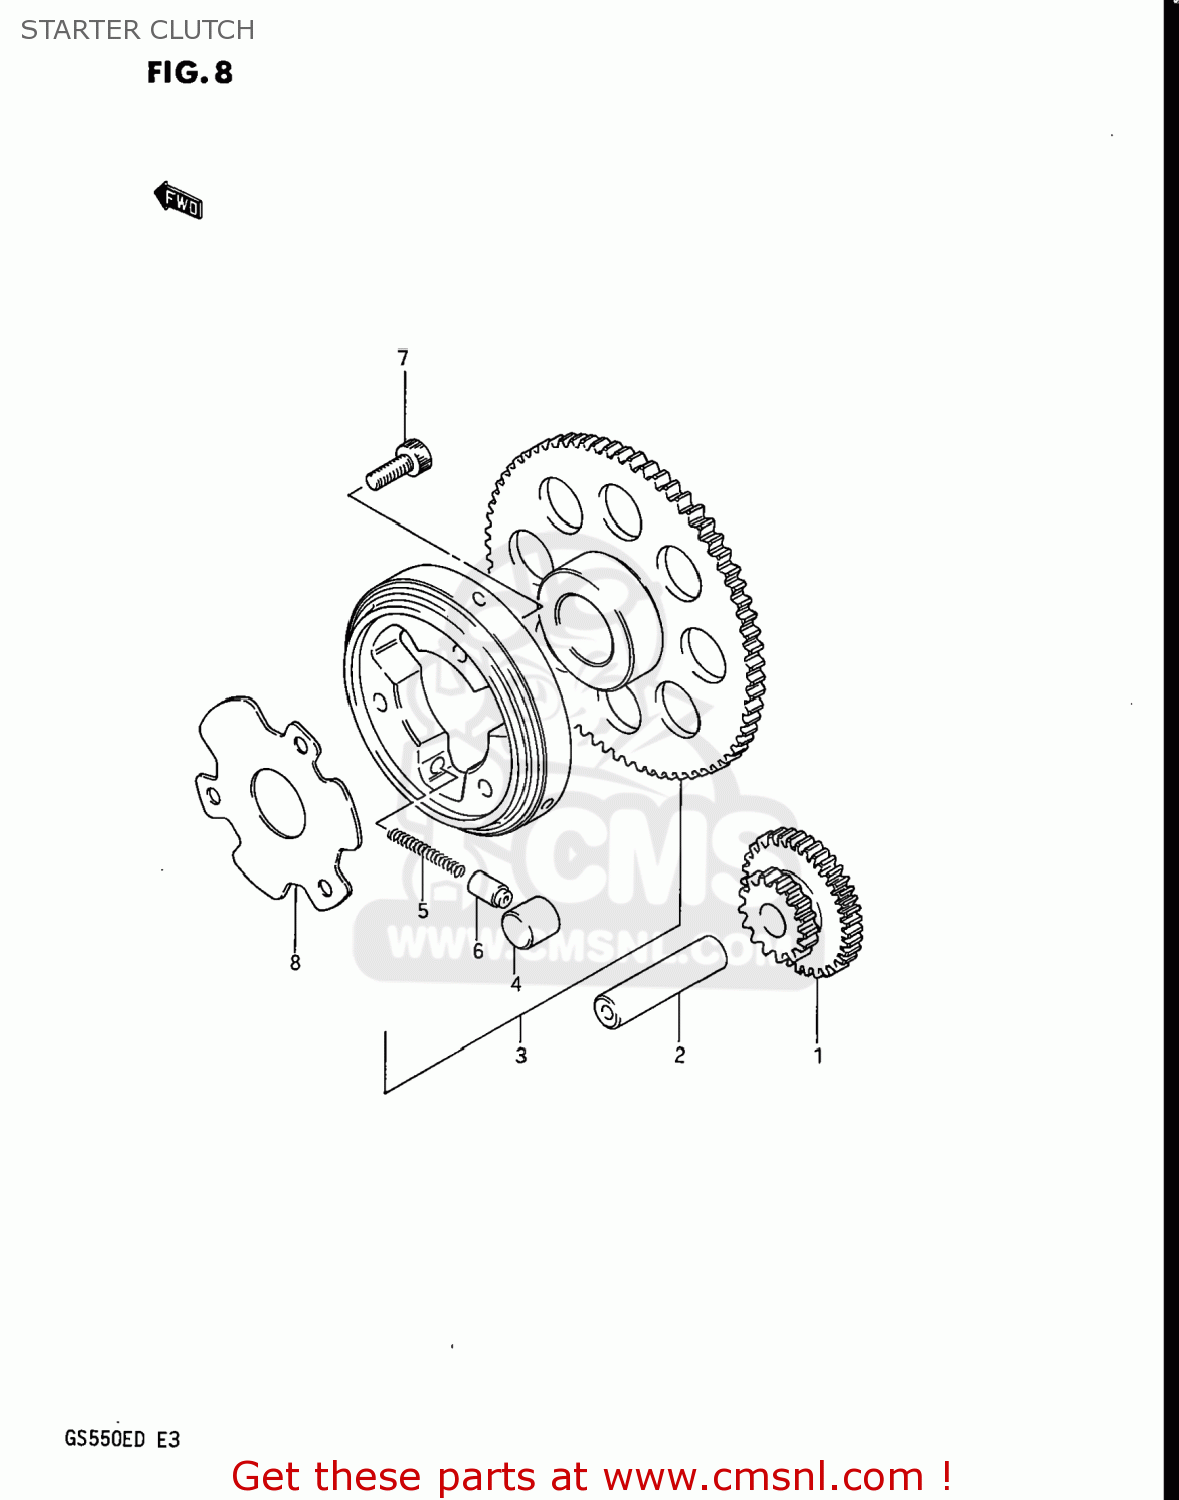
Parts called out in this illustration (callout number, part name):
1	GEAR,STARTER IDLE
2	PIN(7.4X13X56)
3	CLUTCH SET,STARTER
4	PIN(14X13)
5	SPRING
6	PIECE,PUSH
7	BOLT
8	SHIM,STARTER CLUTCH HUB
